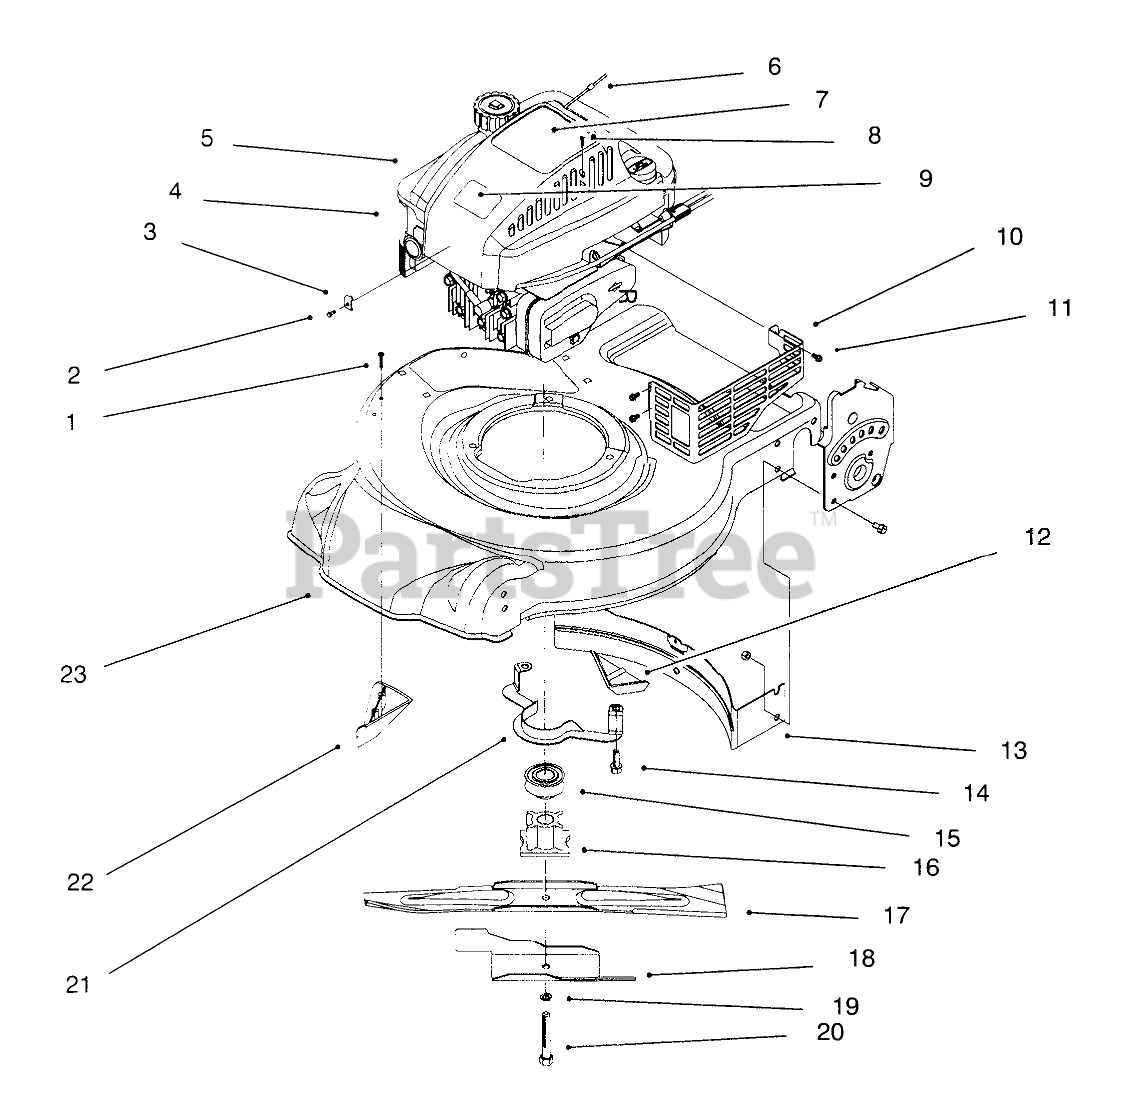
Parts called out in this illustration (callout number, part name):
1	SCREW-PPH
2	SCREW-CLAMP
3	CLAMP-CASING
5	SHROUD-ENGINE
6	STOP-ROPE
7	OBS EXCEPT FOR SERVICE DECAL - ENGINE
8	SCREW-PPH
9	PLATE-LOGO
10	SHIELD-MUFFLER
11	SCREW-HWH
12	KICKER-REAR
13	Baffle-Rear
14	SCREW-HWH
15	PULLEY-DRIVE, ZONE START
16	BLADE RETAINER
17	Blade
18	Accelerator
19	WASHER-LOCK
20	SCREW-BLADE
21	GUIDE - BELT
22	KICKER - SIDE
23	Deck-21" Steel SP (Incl. Ref. #6 pg. 1, Ref. #34 pg. 2, & Ref. #16 pg. 3)
